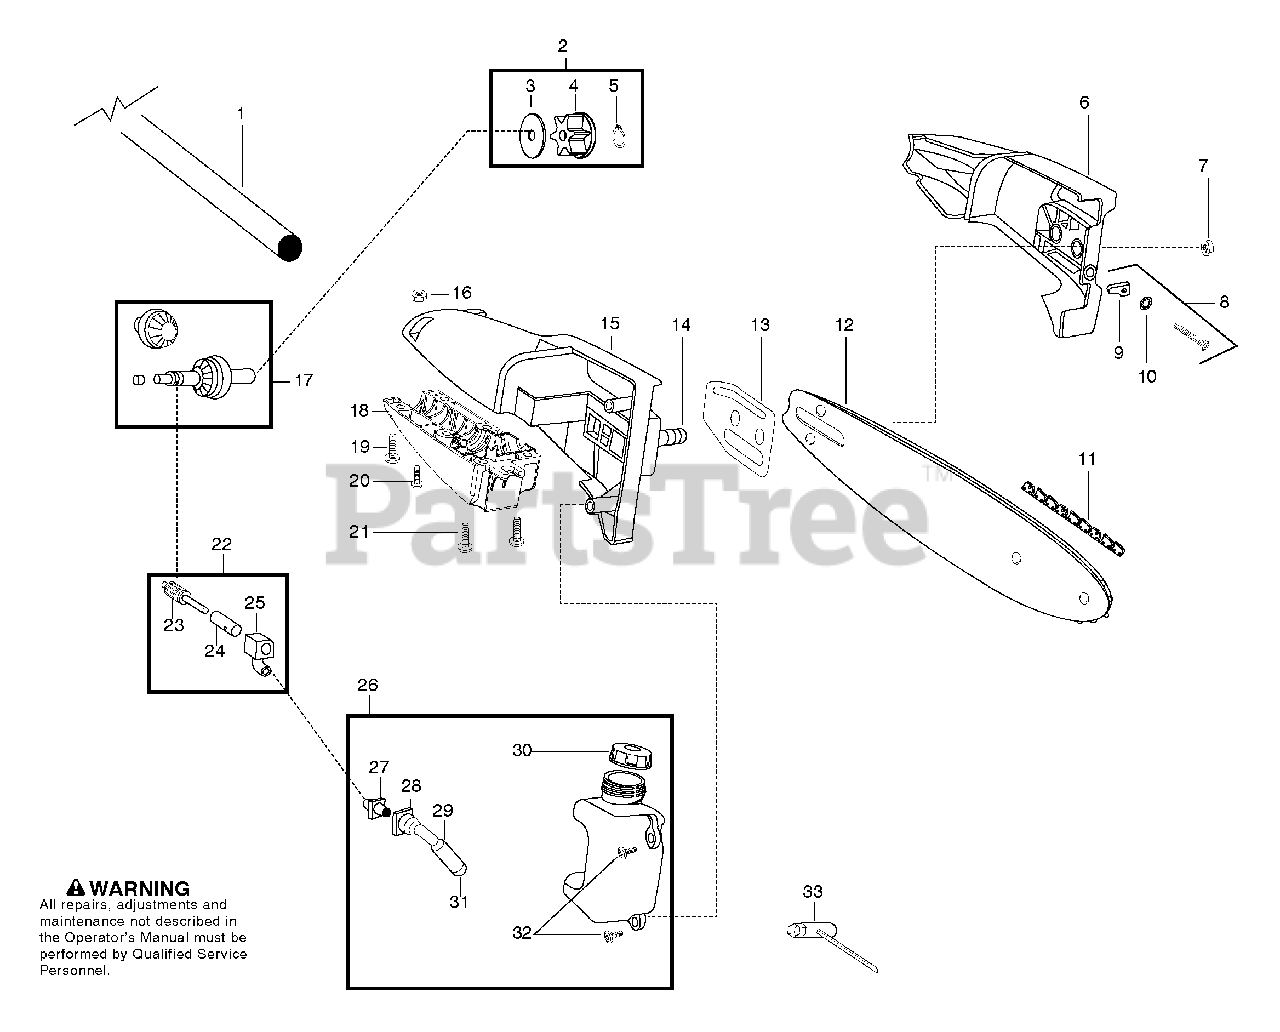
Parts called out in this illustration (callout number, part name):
1	Assy. - Driveshaft
2	Kit - Sprocket Assy.
4	Sprocket
5	Retainer - Sprocket
6	Assy - Bar Clamp
7	Nut - Bar Mounting
8	Kit - Bar Adjust
9	Pin - Bar Adjust
10	Retainer - Bar Adjust
11	Accy - 8" Chain
12	Bar - 8"
13	Plate - Bar Pad
14	Bolt - Bar
15	Housing - Upper
17	Kit - Gear Assy.
18	Housing - Lower
20	Screw - Alignment
22	Kit - Oil Assy
23	Assy. - Gear Plunger
25	Block - Oil
26	Assy - Oil Tank
27	Fitting - Oil Line
28	Intake - Oil Line
29	Filter - Oil
30	Cap - Oil
31	Plug - Oil Filter
33	Wrench - Bar
